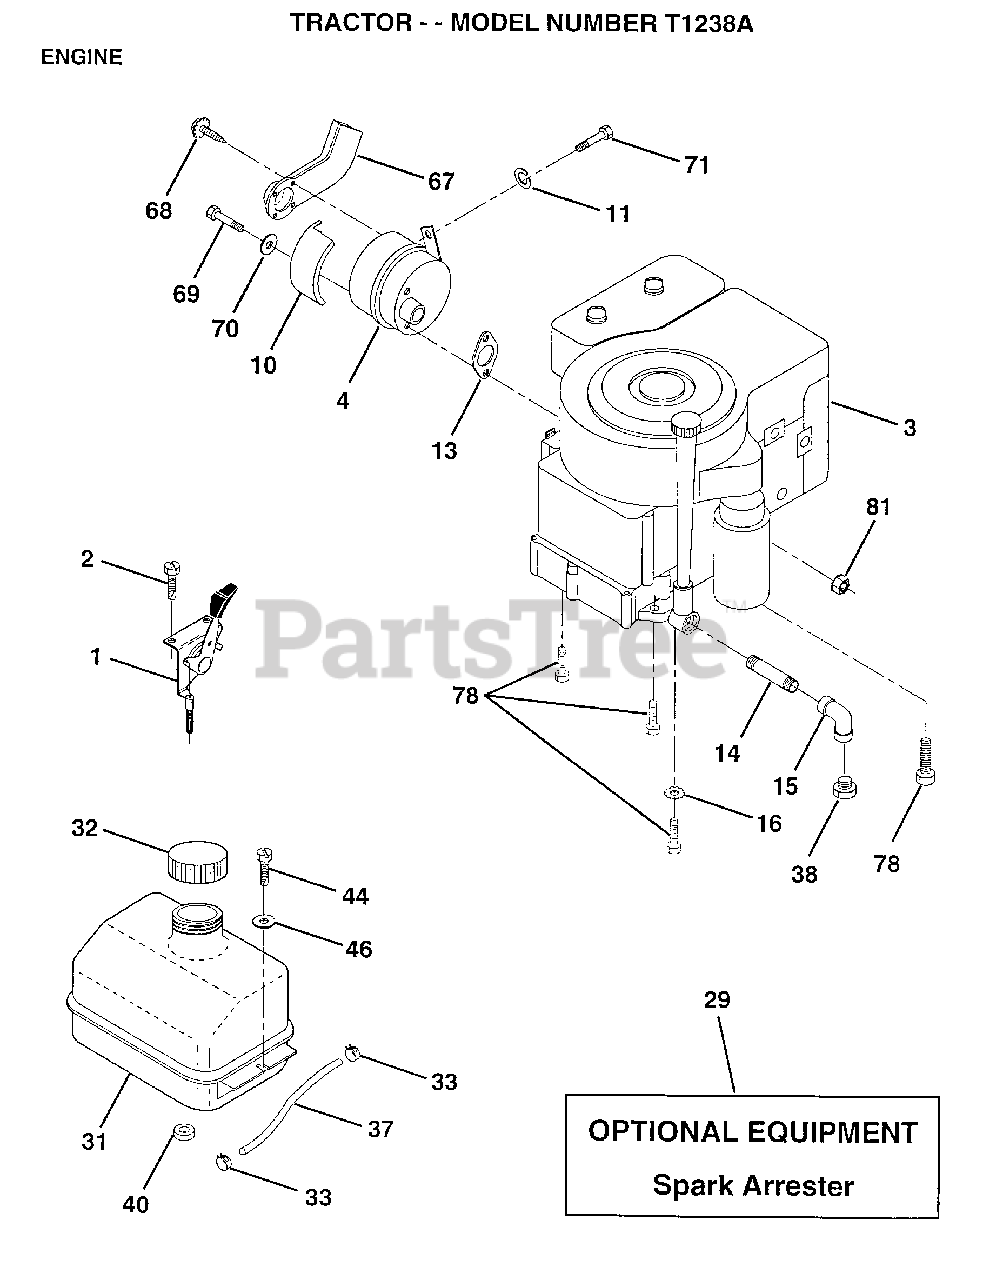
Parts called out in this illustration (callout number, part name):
1	THROTTLE CONTROL
2	SCREW LT
4	MUFFLER LTV
10	SHIELD HEAT LTV
11	LOCKWASHER
13	GASKET ENG 1 313 LD TIN PLATED
14	PIPE NIPPLE
15	ELBOW
16	LOCKWASHER
31	TANK.FUEL.LT.
32	CAP ASM FUEL
33	HOSE CLAMP
37	LINE FUEL
44	SCREW HEX CRT
46	WASHER
67	DEFLECTOR MUFFLER
69	"BOLT,HEX"
70	WASHER T
71	BOLT HXHD FIN
78	SCREW
81	NUT
